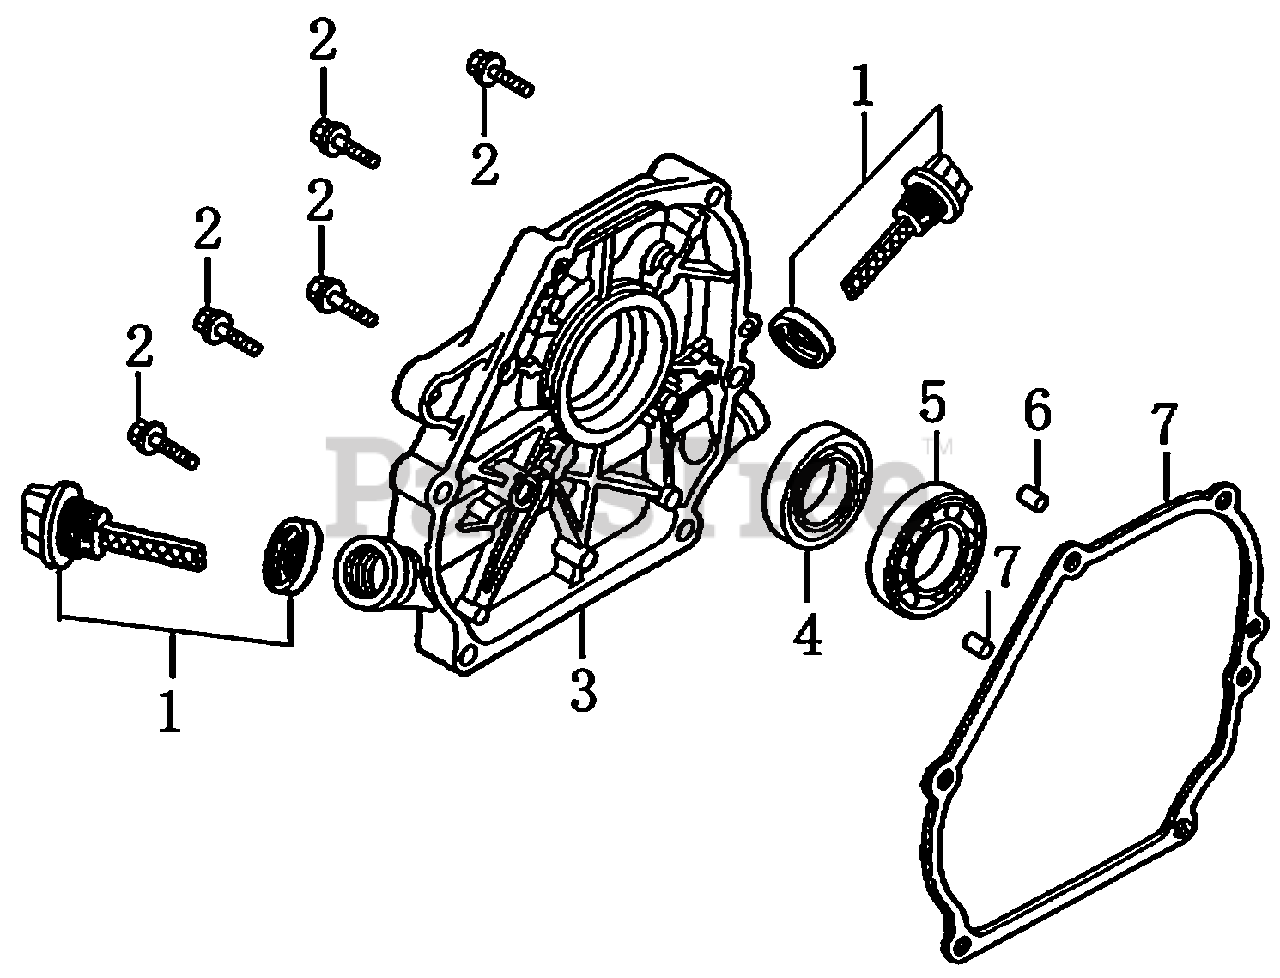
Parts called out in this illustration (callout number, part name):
1	DIPSTICK/ WASHER ASSY.
2	BOLT, FLANGE
3	COVER, CRANKCASE
4	SEAL, OIL
5	BEARING, RADIAL BALL
6	PIN, DOWEL
7	GASKET, CRANKCASE CVR
